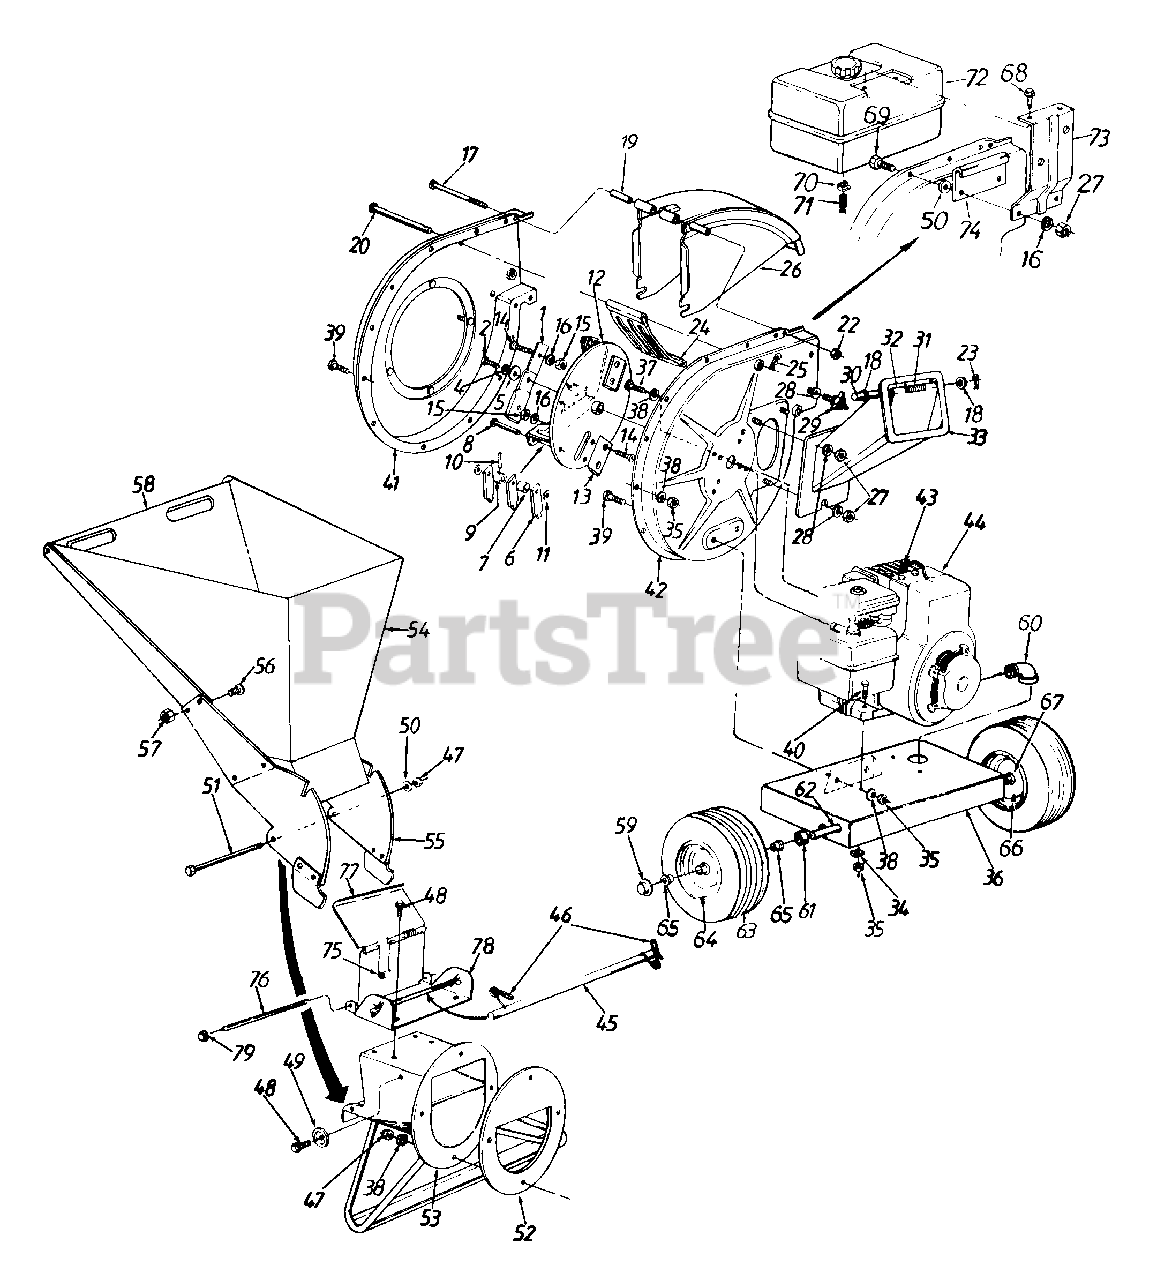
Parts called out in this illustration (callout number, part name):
2	Hex Patch Bolt 3/8-24 x 2.25" (Gr. 8)
4	L-Wash. 3/8" I.D. H.D.
5	FI-Wash..406" I.D. x 1.25" Q.D. Hdn.
6	Flail
7	Flail Spacer
8	Clevis Pin .496" Dia.
9	Flail Spacer w/.160" Dia. Hole
10	Spring Roll Pin 1.125" Lg.
11	FI-Wash..531" I.D. x .94" O.D.
12	Impeller Ass'y. Comp.
13	Chipper Blade
14	Flat Hd. Scr. 5/16-24 x .75" Lg.
15	Hex Top L-Nut 5/16-24 (Gr. 5)
16	L-Wash. 5/16" I.D.
17	Hex Bolt 1/4-20 x 3.75" Lg.
18	FI-Wash..281" I.D. x.5" O.D.
19	Chute Hinge Spacer 1.66" Ig.
20	Clevis Pin .5" Dia. x 4.62" Lg.
22	Hex Ctr. L-Nut 1/4-20 Thd.
23	Cotter Pin
25	Internal Cotter Pin 3/8" Dia.
27	Hex Nut 5/16-18 Thd. (Gr. 5)
28	Bell-Wash..345" I.D. x .88"
29	Hand Knob
30	Chipper Door Rod
31	Torsion Spring 1.14" Lg.
35	Hex Nut 5/16-18 Thd. (Gr. 5)
38	L-Wash. 5/16" I.D.
39	Hex Bolt 5/16-18 x .75" Lg. (Gr. 5)
40	Hex Bolt 5/16-18 x 1.75" Lg.
44	Engine
45	Release Bar
46	Torsion Spring 1.06" Lg.
47	Elastic Lock Nut 5/16-18 Thd.
48	Hex Wash Hd. Self-Tap Scr. 5/16-18 x .75" Lg.
49	Stop Washer
50	Fl-Wash. 5/16" I.D.
51	Hex Bolt 5/16-18 x 8 38" Lg.
57	Hex L-Nut 1/4-20 Thd.
60	Drain Elbow
61	Spacer 64" I.D. x .38" Lg.
62	Shredder Axle
66	Air Valve
67	Grease Fitting
68	Hex Hi-Low Scr. 1/4" x .75" Lg.
69	Hex Bolt 5/16-18 x .88" Lg.
70	Hose Clamp
71	Fuel Line -- 7" Lg.
72	Fuel Tank Ass'y. Comp.
76	Hopper Door Rod
11461B-0498	RAMP SECTI - OLD CUB YELLOW (0498)
11461B-0629	RAMP SECTI - SILVER FLAKE (0629)
11461B-0638	RAMP SECTI - MTD/TROY-BILT RED (0638)
11461B-0662	RAMP SECTI - OYSTER GRAY (0662)
16522B-0498	GUIDE ASSEMBLY-INLET (CUB YELLOW) - OLD CUB YELLOW (0498)
16522B-0637	GUIDE ASSEMBLY-INLET - POWDER BLACK (0637)
16522B-0638	GUIDE ASSEMBLY-INLET - MTD/TROY-BILT RED (0638)
16522B-0662	GUIDE ASSEMBLY-INLET (OYSTER GRAY) - OYSTER GRAY (0662)
16524B-0498	GUIDE ASSEMBLY-UPR (CUB YELLOW) - OLD CUB YELLOW (0498)
16524B-0638	GUIDE ASSEMBLY-UPR (MTD RED) - MTD/TROY-BILT RED (0638)
16524B-0648	GUIDE ASSEMBLY-UPR (TECH GRAY) - TECH GRAY (0648)
16524B-0662	GUIDE ASSEMBLY-UPR (OYSTER GRAY) - OYSTER GRAY (0662)
